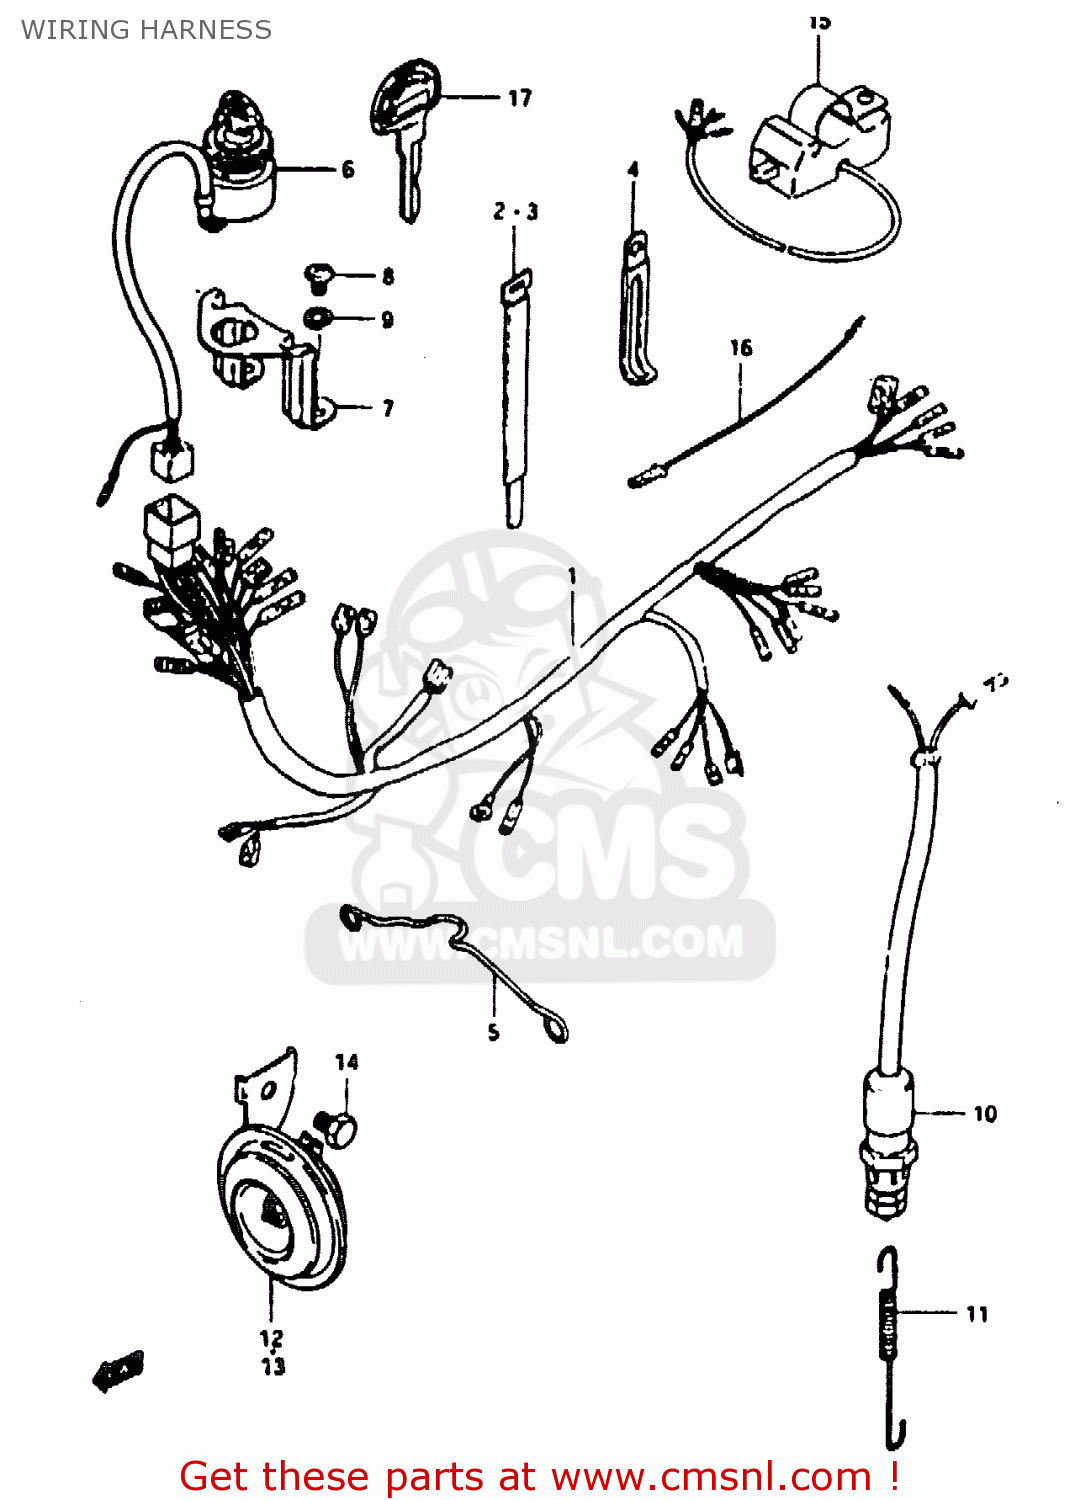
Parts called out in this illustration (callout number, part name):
1	WIRING HARNESS
2	CLAMP
3	CLAMP L:110
4	CLAMP
5	CLAMP
6	SWITCH ASSY, IGNITION
7	BRACKET,IGNITION SWITCH
8	SCREW
9	LOCK WASHER
10	SWITCH ASSEMBLY,STOP LAMP
11	SPRING
12	HORN
14	BOLT
17	KEY,BLANK
